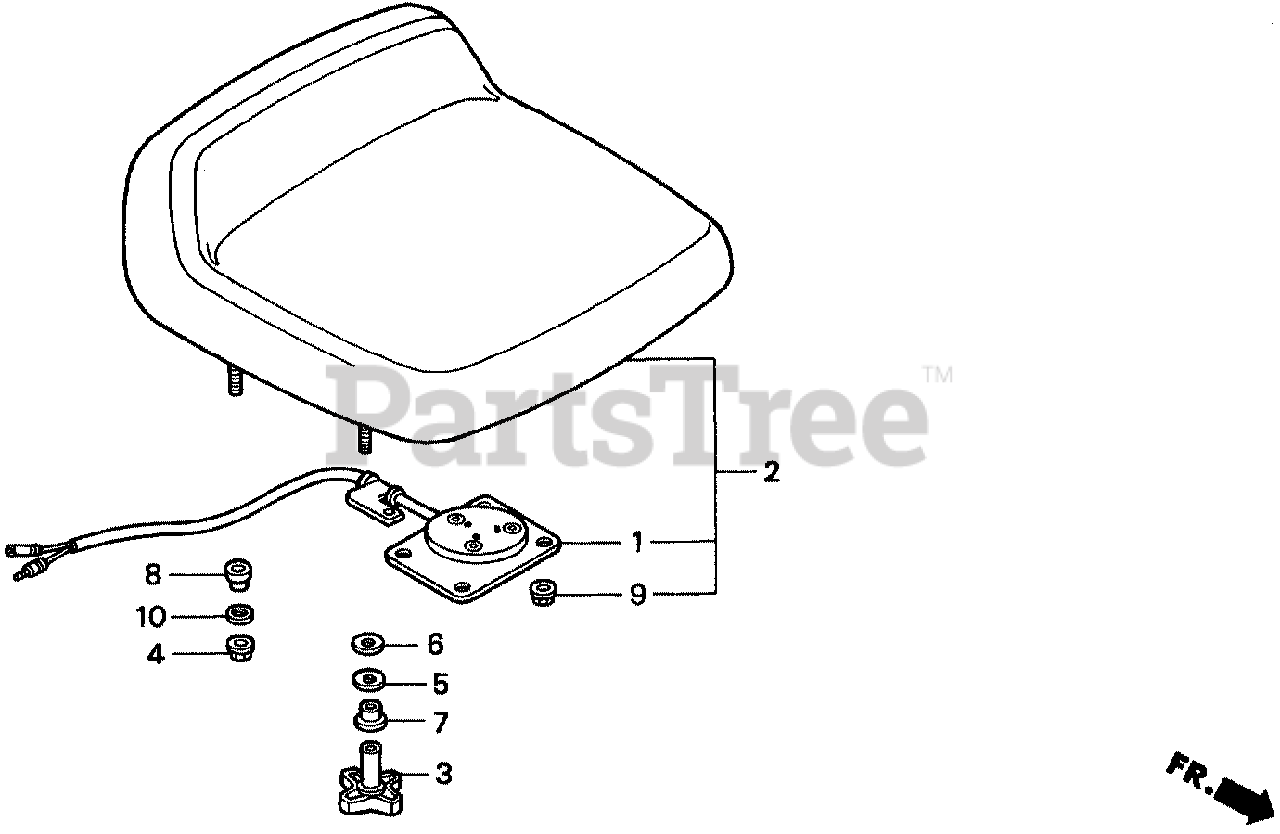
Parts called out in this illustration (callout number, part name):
1	SWITCH ASSY., SEAT (NOT AVAILABLE)
1	SWITCH ASSY., SEAT
2	SEAT ASSY.
3	GRIP, SEAT
4	NUT, U (6MM) (FUSE RASHI)
5	WASHER, SPRING (10MM)
6	WASHER (6X20)
7	COLLAR, SEAT
8	COLLAR, SEAT SLIDE
9	NUT, FLANGE (6MM)
10	WASHER, PLAIN (6MM)
